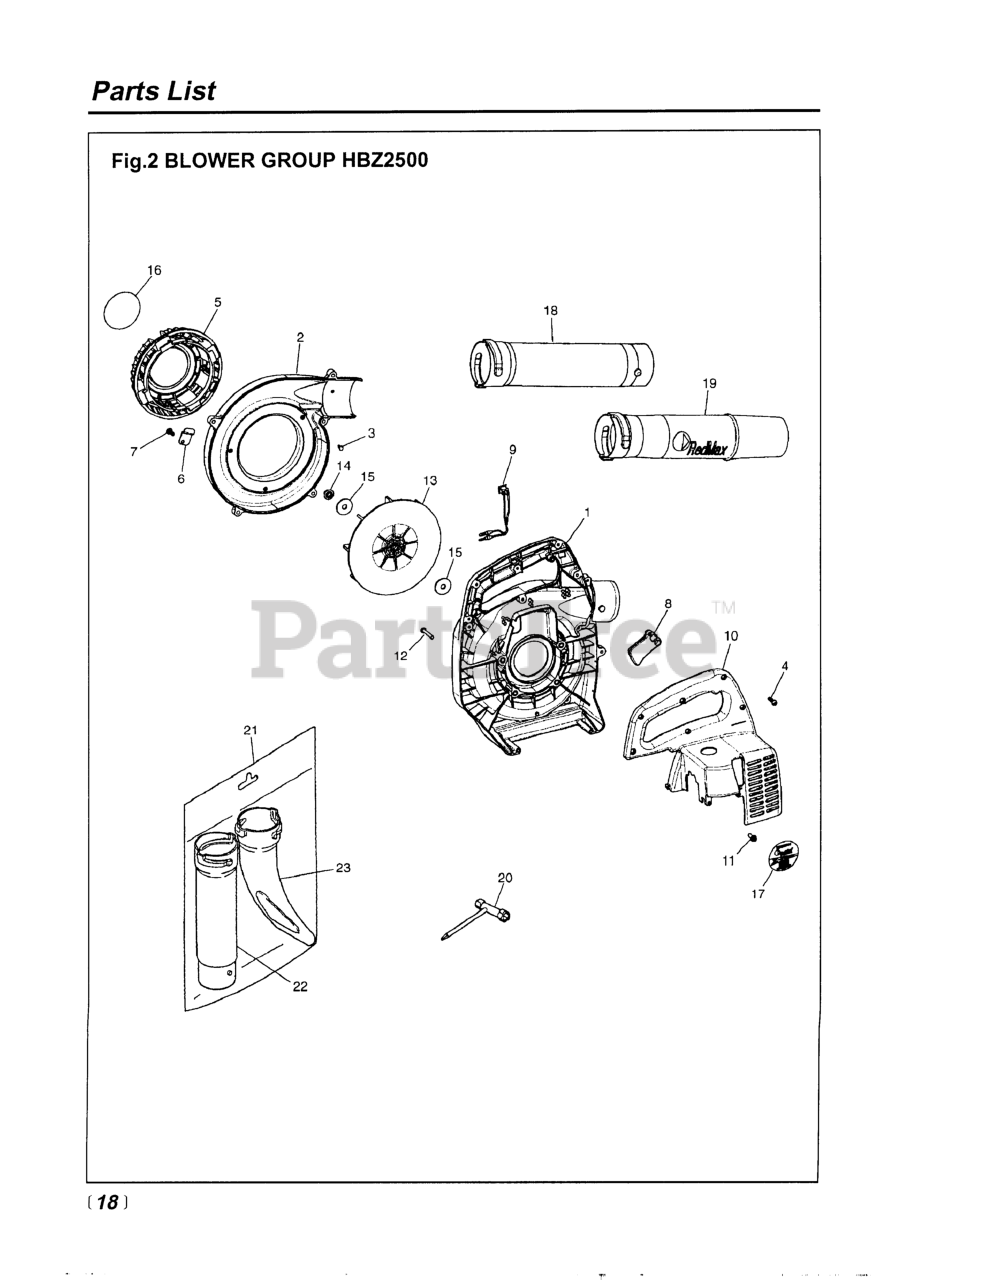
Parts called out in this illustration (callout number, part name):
1	848-L0F-55A1
2	VOLUTE COVER (HBZ 2500)
3	SCREW
5	GUARD
8	LEVER
9	SWITCH
10	ENGINE COVER
11	BOLT
12	SCREW
13	FAN
15	WASHER
17	LABEL, RECOIL
19	PIPE, END
21	FLAT NOZZLE SET
23	NOZZLE, FLAT
